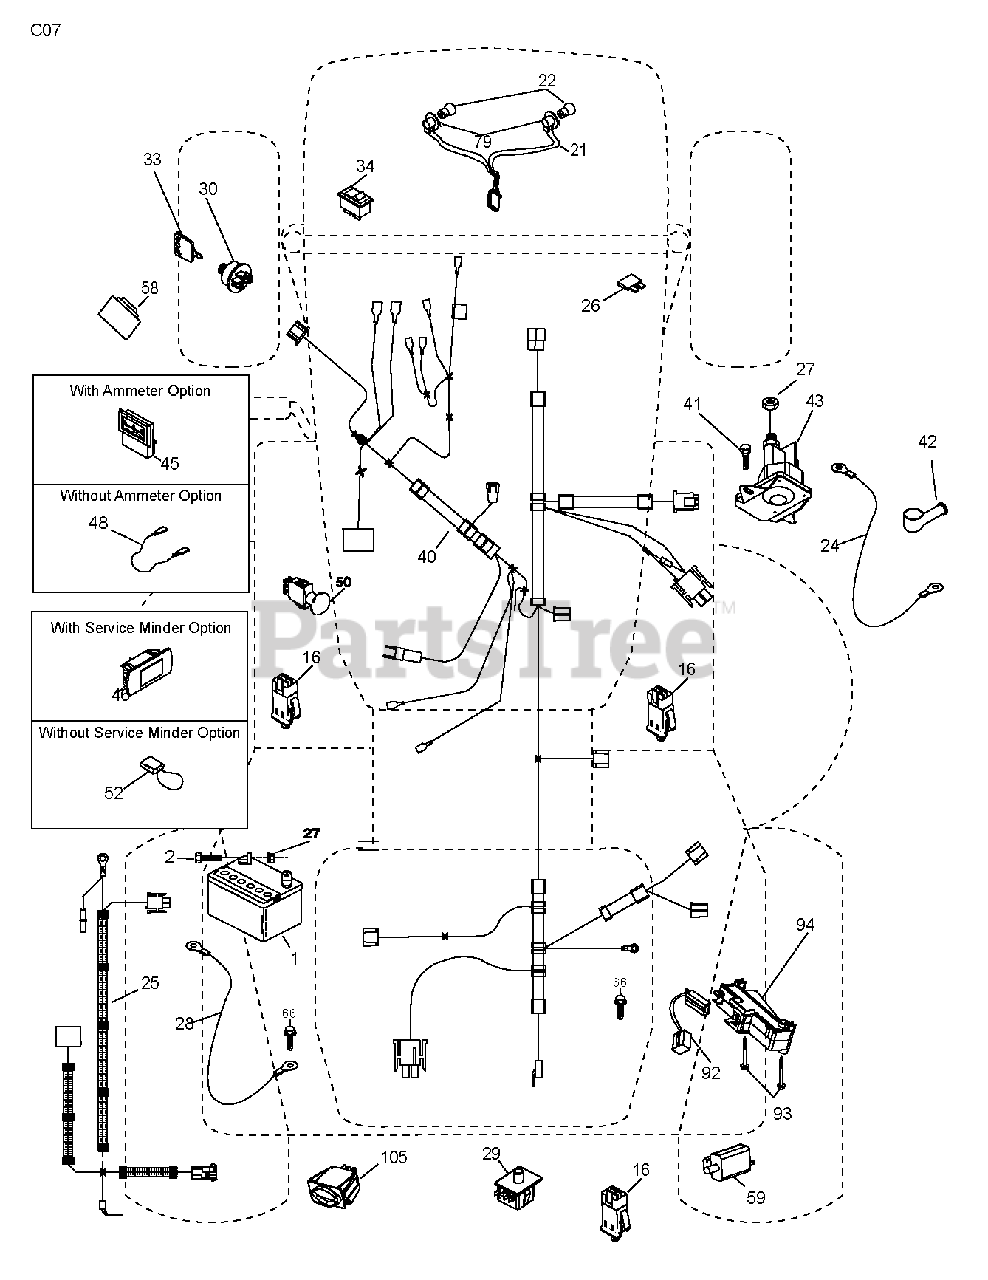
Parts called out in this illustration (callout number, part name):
1	Battery, Dry 30 Amp
2	BOLT.HEX.1/4.X.3/4.DICHROMATE
16	SWITCH INTERLOOK PUSH-IN
21	HARNESS.LIGHT W/4152J BULBS
24	CABLE.STARTER.6GA.11"RED
26	FUSE 20AMP
27	NUT
28	CABLE GROUND
29	SWITCH.SEAT.DP W/RAMPS
30	SWITCH.IGN.DELTA.W.LGH.ROS
33	KEY.CHAIN.BLISTER.PACK.GEN.INT
41	BOLT
42	TERMINAL COVER
43	SOLENOID.W/BRASS.PLUNGER
46	RP GUAGE.SRVCMNDR.HRMTR.
48	ADAPTER.AMMETER
50	RB PTO.SWITCH.8 TERMINAL.BLACK
58	BUZZER
59	.WITCH.FULL BAGGER.INDICATOR
79	BULB HOLDER ASM.
92	HARNESS.PIGTAIL.CONSLE
93	SCREW.PLASTITE
94	MODULE.REVERSE.ROS
